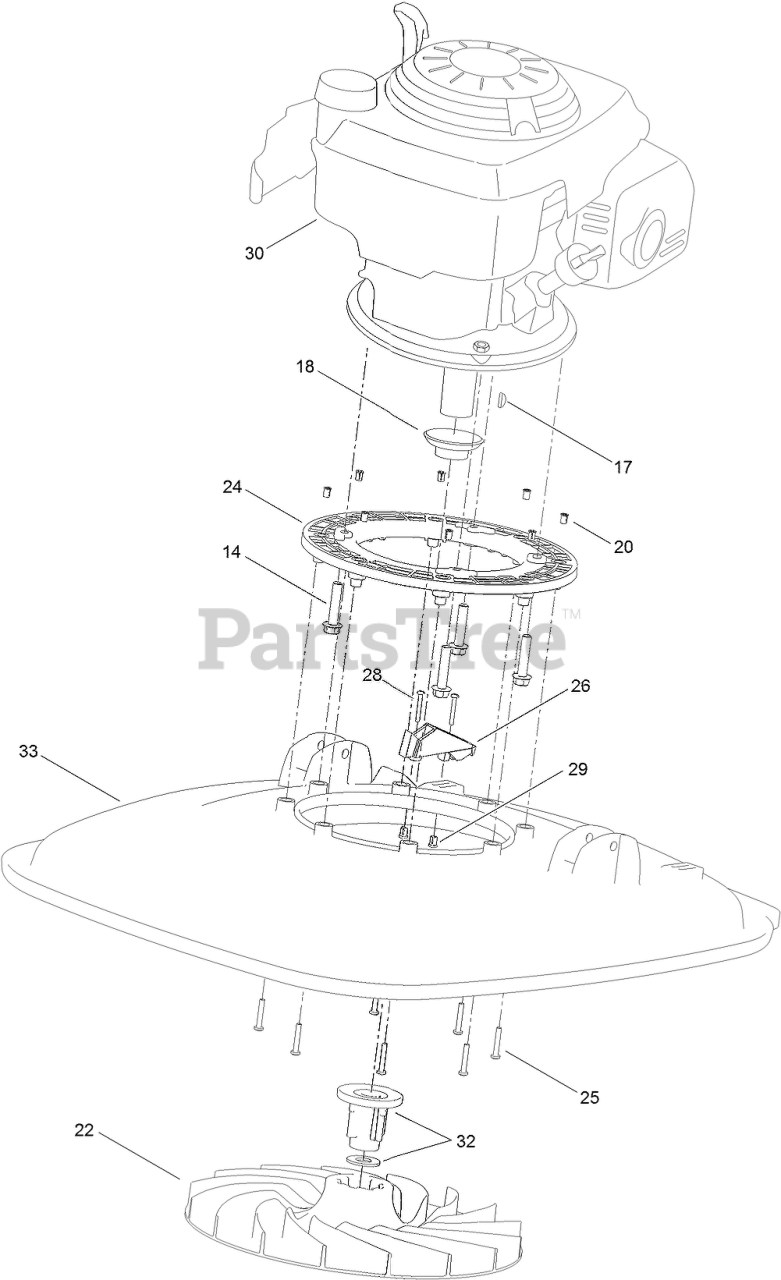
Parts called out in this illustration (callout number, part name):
14	SCREW-TAPTITE
17	KEY-WOODRUFF
18	PROTECTOR-SEAL, OIL
20	INSERT-BRASS
22	IMPELLER
24	FRAME-MOUNTING, ENGINE
25	SET-SCREW
26	BRACKET
28	SCREW
29	INSERT
30	ENGINE-HONDA
32	DRIVE AND SPACER ASM
33	DECK-DRILLED
